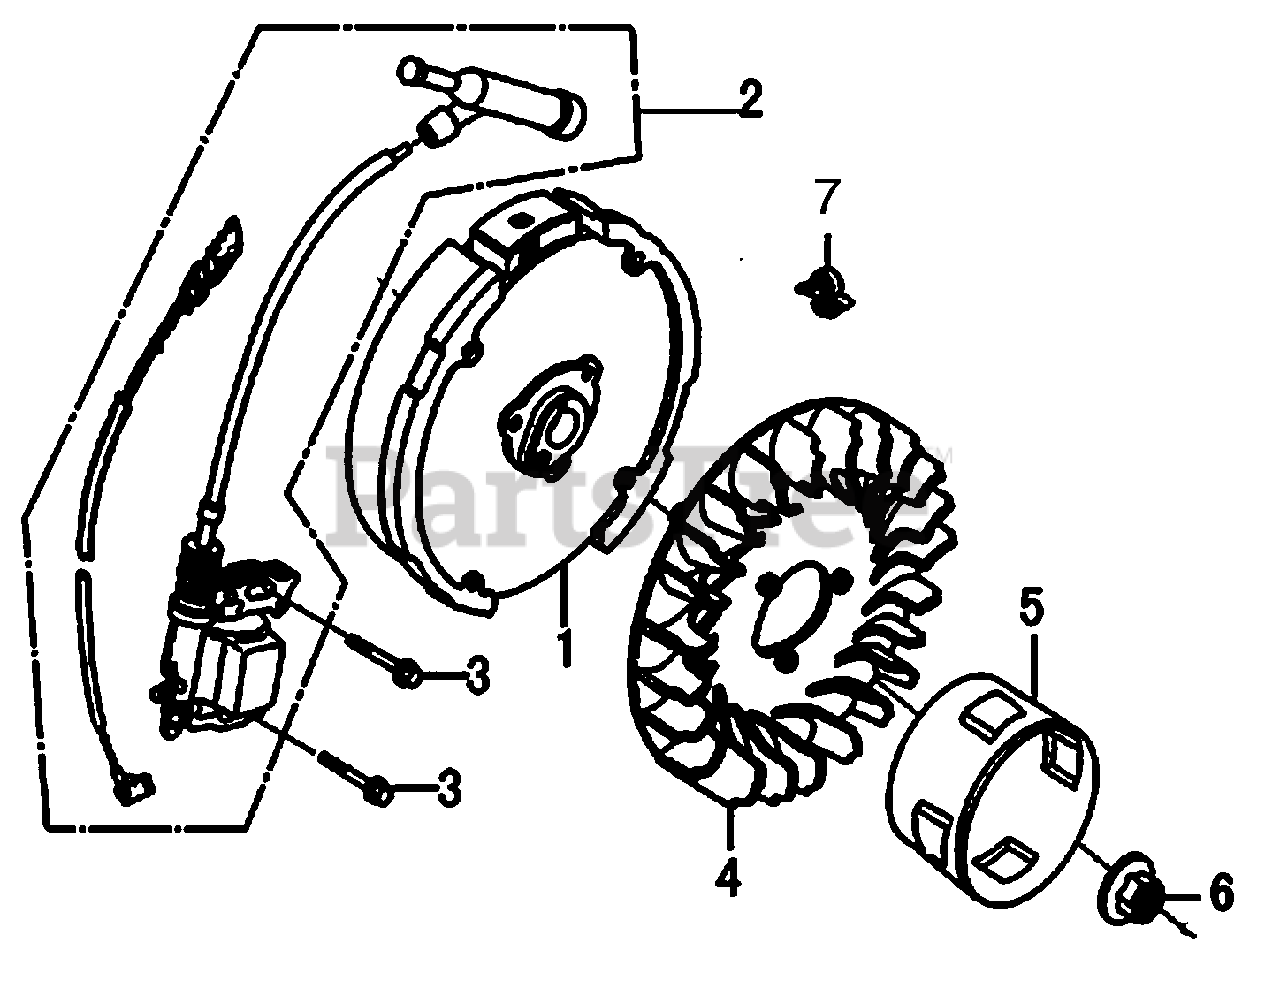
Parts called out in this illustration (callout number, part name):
2	COIL ASSY., IGNITION
3	BOLT, FLANGE,6X25
4	FAN, COOLING
5	PULLEY, STARTER
6	NUT, SPECIAL
7	CABLE CLIP
